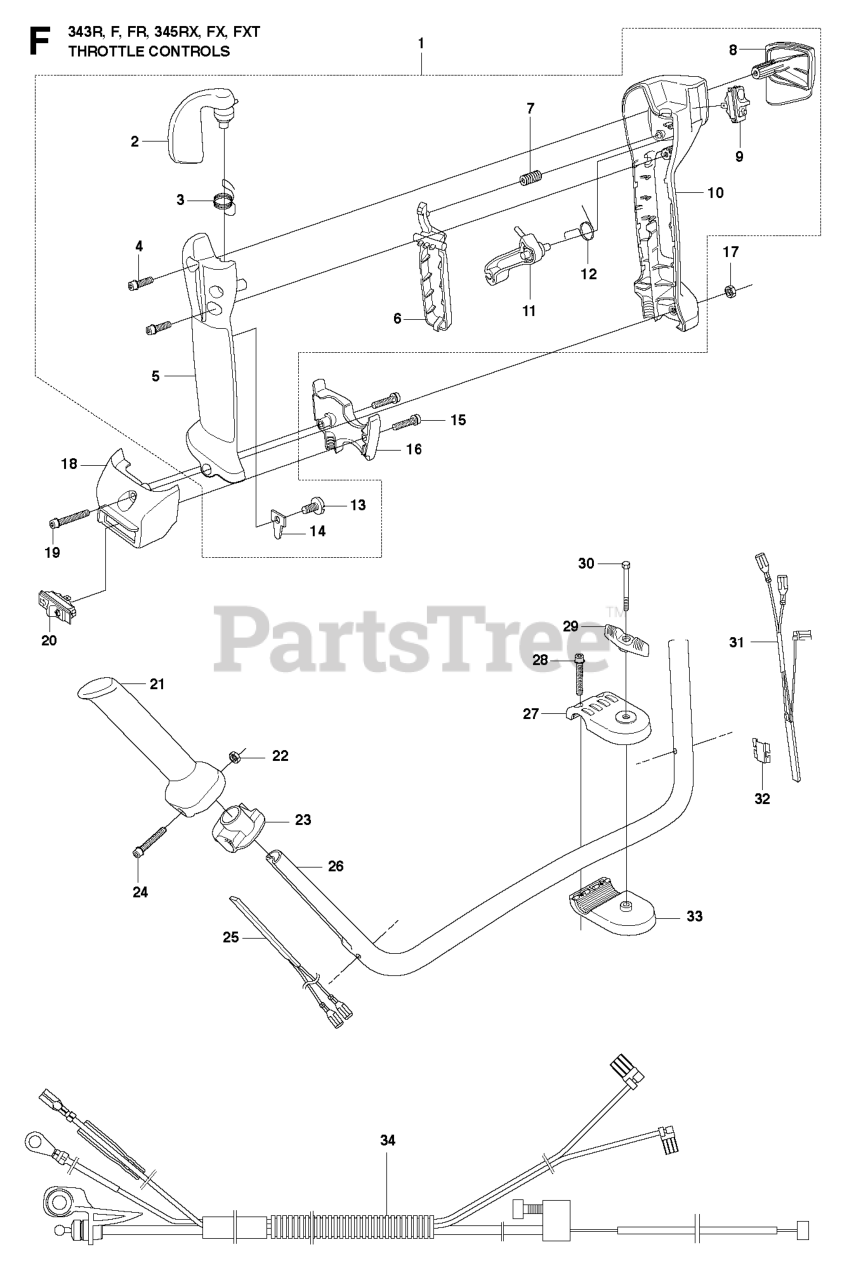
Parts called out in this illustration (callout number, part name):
1	THROTTLE HANDLE
2	THROTTLE TRIGGER
3	RP SPRING
5	HANDLE
6	THROTTLE LOCK
9	STOP BUTTON
10	HANDLE
15	SCREW
16	HOLDER
17	NUT M6M M5
18	HOLDER
19	SCREW
20	SWITCH (G)
21	HANDLE
22	NUT M6M M5
25	HEATING ELEMENT
26	RP HANDLE
26	%HANDLE
27	HANDLE HOLDER UPPER
30	%SCREW
31	HEATING ELEMENT
32	HOLDER
33	HANDLE HOLDER LOWER
34	WIRING ASSY
